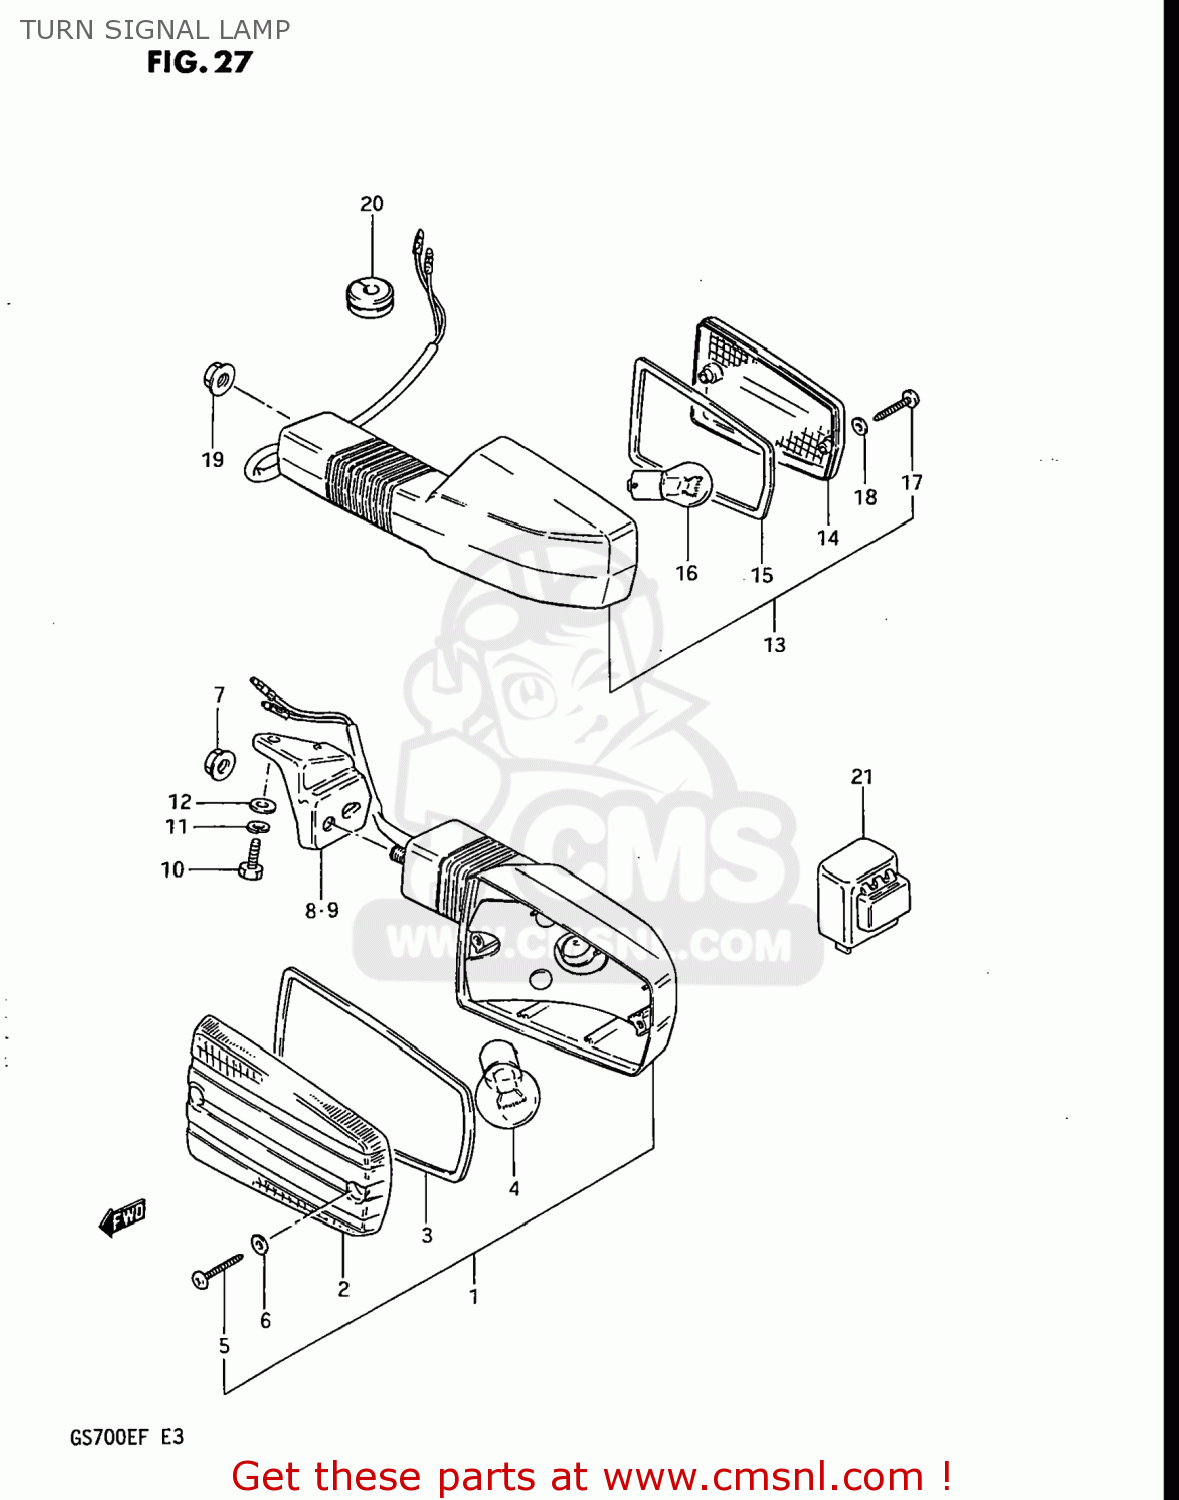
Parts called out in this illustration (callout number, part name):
1	LAMP ASSEMBLY,FRONT TURN SIGNAL
2	LENS,TURN SIGNAL LAMP
3	GASKET (NAS)
4	BULB(12V23W)
5	SCREW
6	GASKET (NAS)
7	NUT
8	BRACKET,FRONT TURN SIGNAL
9	BRACKET,FRONT TURN SIGNAL
10	BOLT
11	WASHER,LOCK,8.
12	WASHER
13	LAMP ASSY,RR TURNSIGNAL
14	LENS
15	GASKET (NAS)
16	BULB(12V23W,STANLEY,A4577A)
17	SCREW
18	GASKET (NAS)
19	NUT
20	GROMMET
21	RELAY ASSEMBLY,TURN SIGNAL
